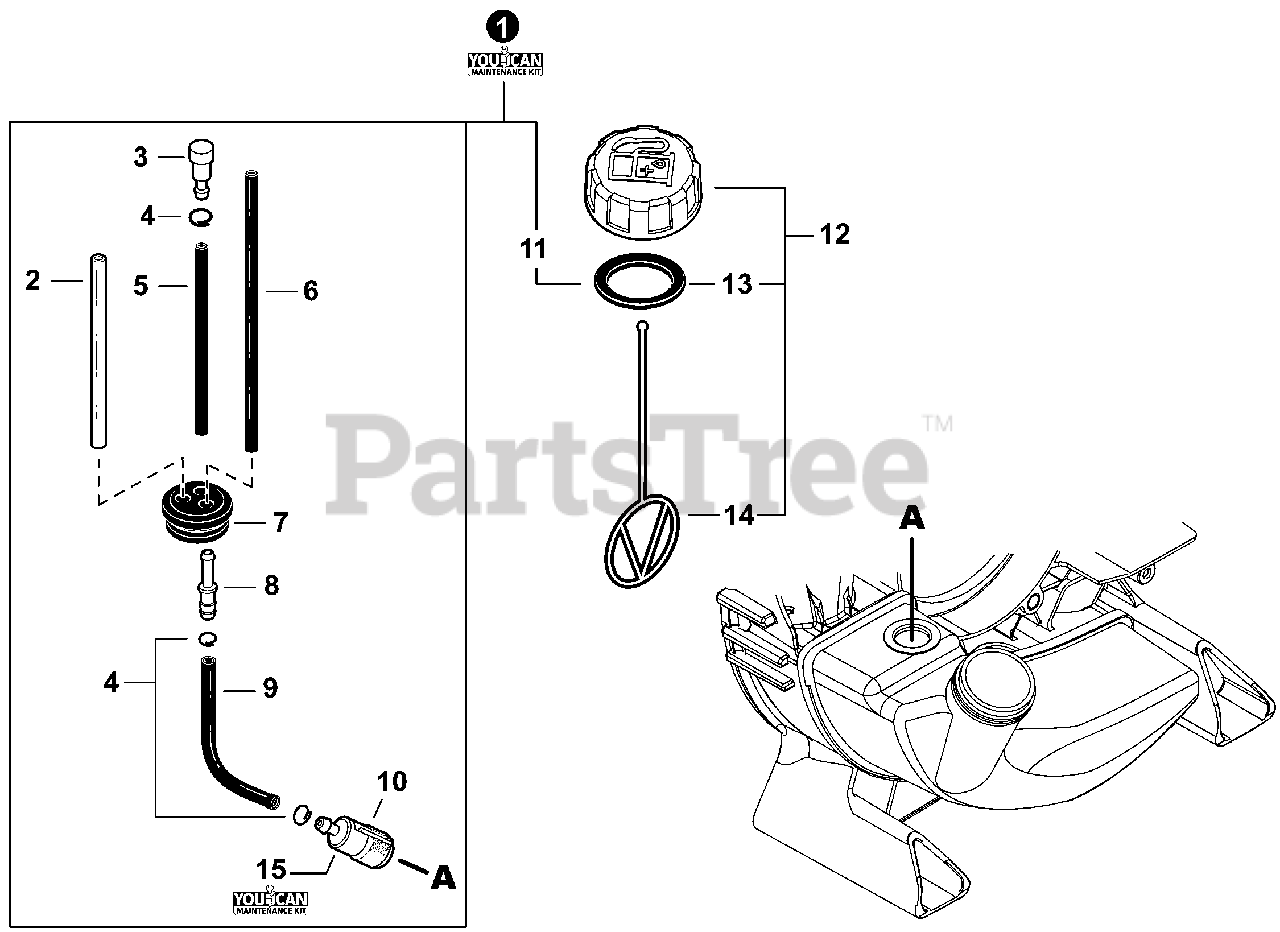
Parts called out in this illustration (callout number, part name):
1	FUEL SYSTEM KIT - YOUCANT
2	PIPE, FUEL 3×6×85 CLEAR
3	VENT ASSY
4	CLIP Ø6
5	PIPE, FUEL 3×5×60 BLACK
6	PIPE, FUEL 3×5×80 BLACK
7	GROMMET, FUEL Ø5
8	CONNECTOR, PIPE Ø5ר3.5
9	PIPE, FUEL 3×5×140 BLACK
10	FILTER, FUEL
11	GASKET, FUEL CAP
12	CAP ASSY, FUEL
13	GASKET, FUEL CAP
14	CONNECTOR, CAP L= 100 MM
15	TUNE-UP KIT - YOUCANT
